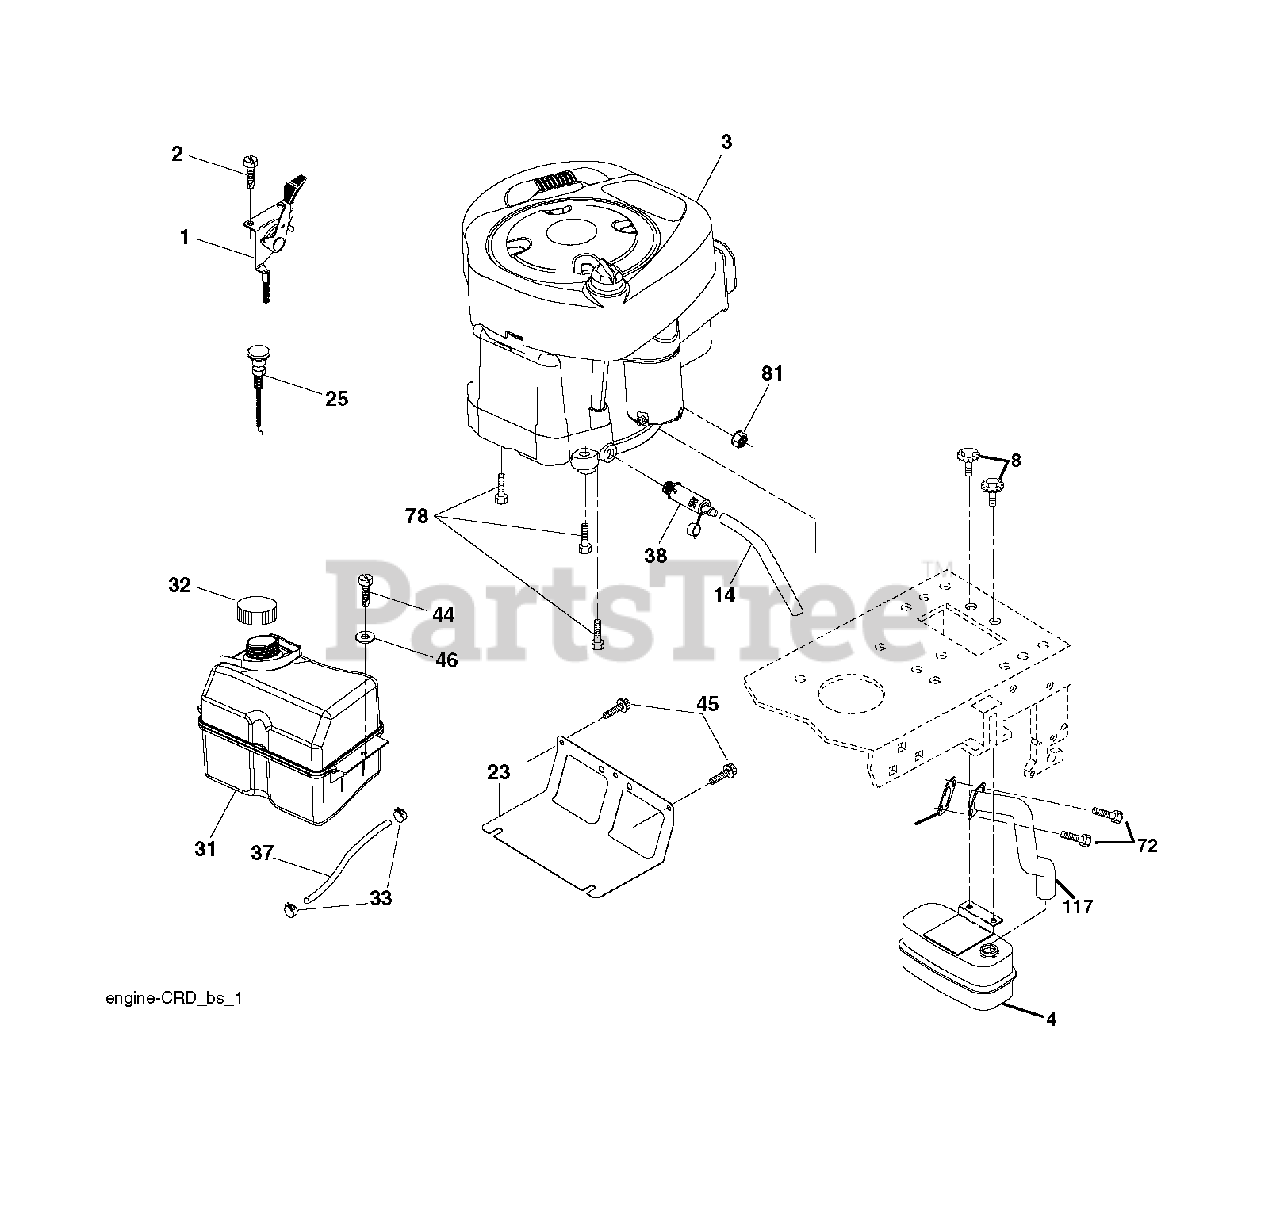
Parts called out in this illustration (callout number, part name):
1	CONTROL TH/CH FLAG
2	SCREW
4	MUFFLER.SINGLE.CYL.KOHL/B&S
8	BOLT, 5/16-18 X 1 3/4
13	REPL BY 532 27 22-93
14	TUBE, DRAIN OIL ASM.
23	SHEILD.BROWNING.DBR.GUARD
29	ARRESTER SPARK (OPTIONAL)
32	FUEL CAP
33	HOSE CLAMP
37	LINE.FUEL.20
38	PLUG DRAIN OIL EASY
44	SCREW HEXWSHR 1/4-20X3/4
45	SCREW, 3/8-16X3/4
72	SCREW.SOCKET HD.5/16-1
78	SCREW.3/8-16
81	NUT
117	EXHAUST.TUBE.B&S.
